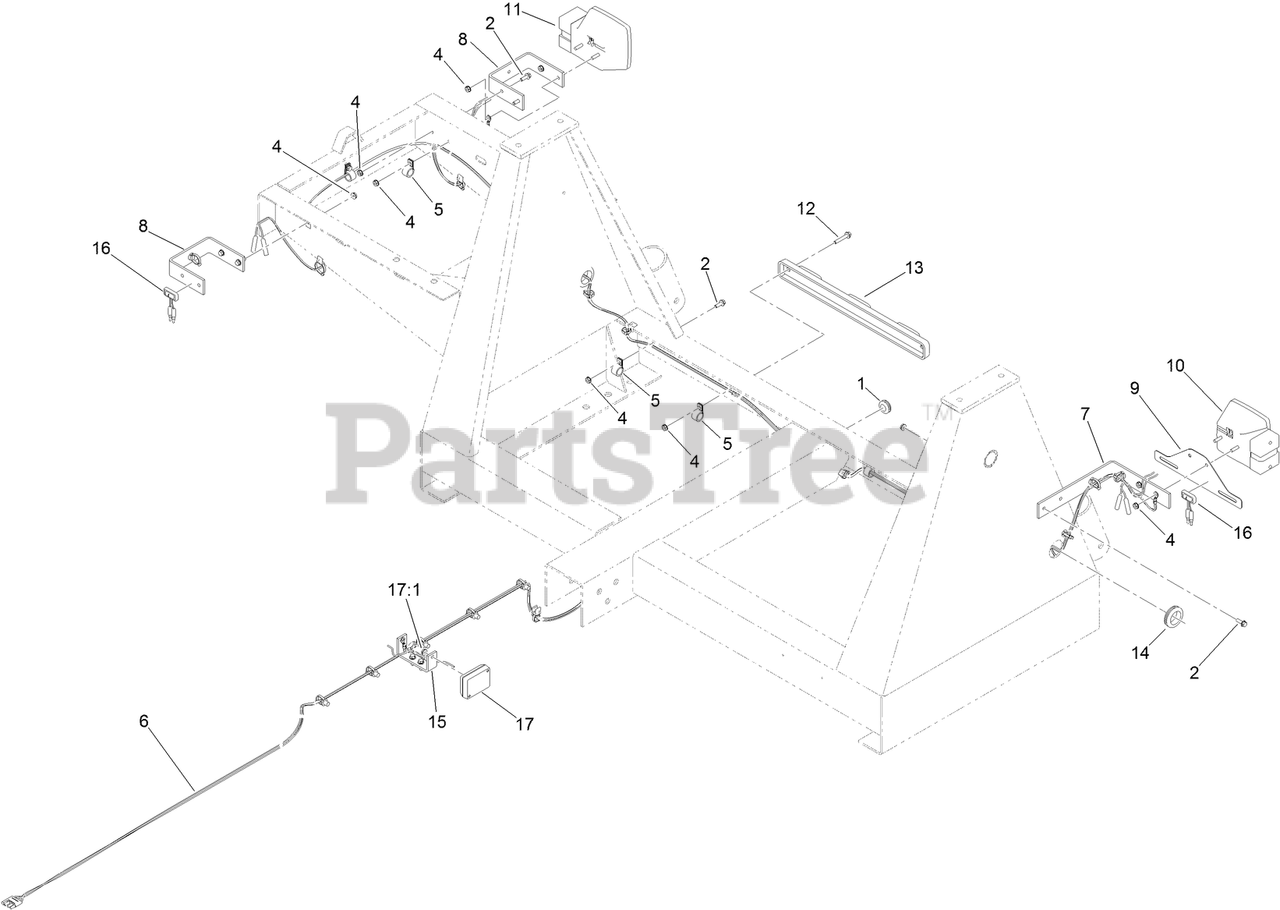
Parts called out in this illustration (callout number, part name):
1	GROMMET
2	SCREW-HHF
4	NUT-KEPS
5	CLAMP-CABLE
6	HARNESS-WIRE
7	BRACKET-L
8	BRACKET-U
9	HOLDER-PLATE, LICENSE
10	LIGHT-TAIL, LH
11	LIGHT-TAIL, RH
12	SCREW-HHF
13	LIGHT-IDENTIFICATION, TRAILER
14	GROMMET
15	BRACKET-LIGHT
16	LAMP-AMBER
17	LAMP-MARKER, FRONT SIDE
17:1	NUT-KEPS
